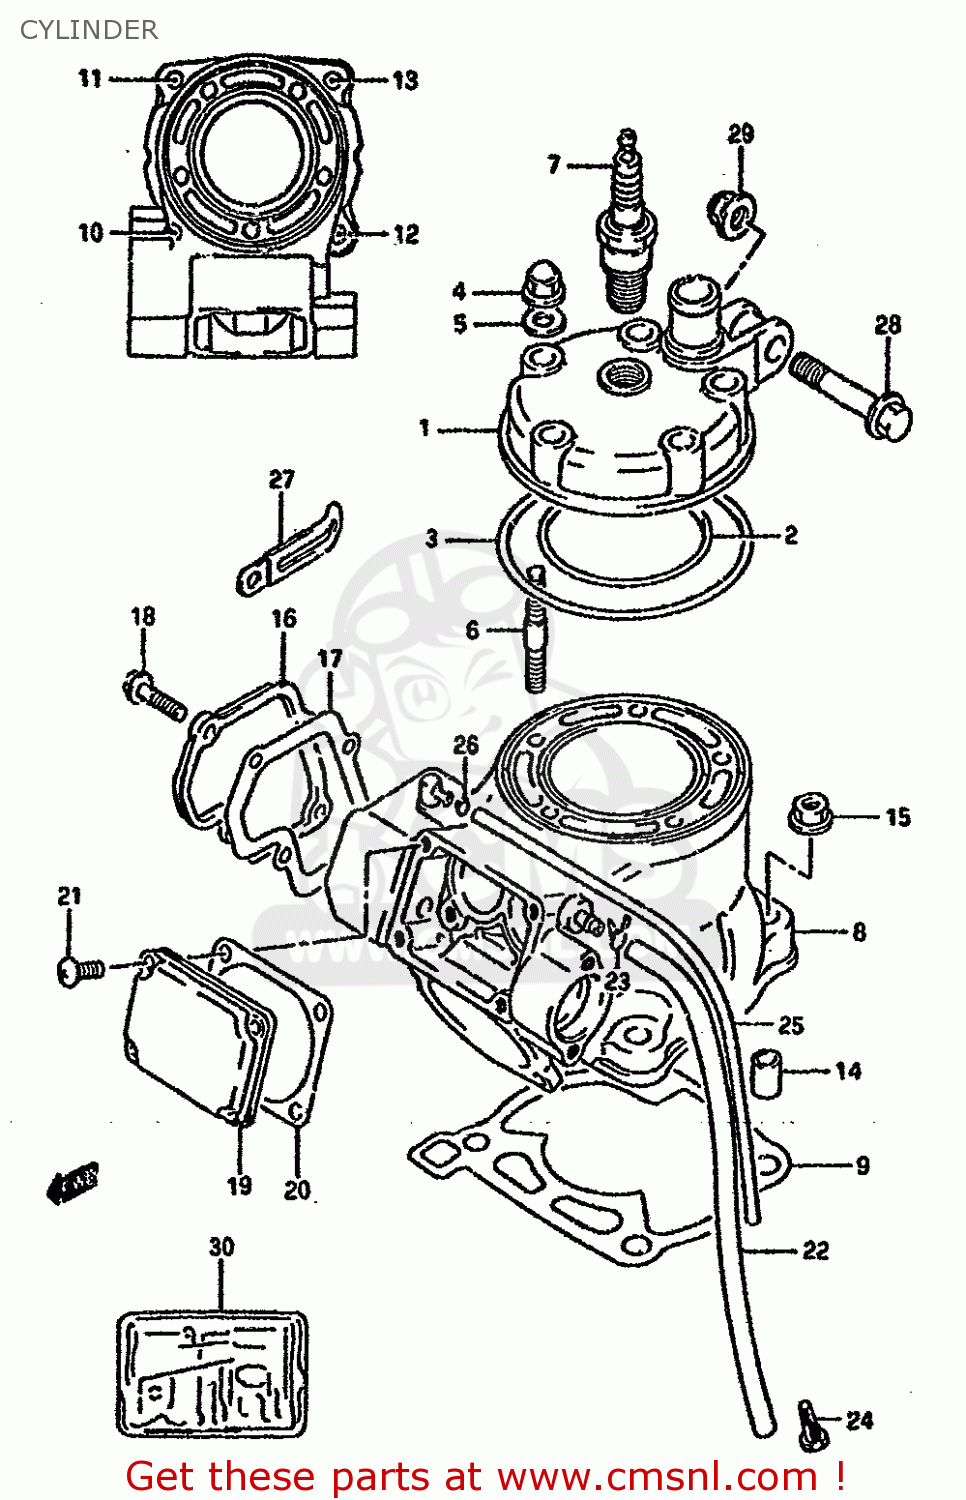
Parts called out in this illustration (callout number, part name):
1	HEAD,CYLINDER
2	O RING,CYLINDER HEAD NO.1
3	O RING,CYLINDER HEAD NO.2
4	NUT
5	GASKET(8.5X17X2.3) (NAS)
6	BOLT,STUD
7	SPARK PLUG BR9EV
8	CYLINDER
9	GASKET,CYLINDER (NAS)
10	STUD 8X25
11	BOLT,STUD
12	STUD BOLT
13	BOLT,STUD
14	PIN(8.4X11X14)
15	NUT
16	COVER,CYLINDER NO.1
17	GASKET,CYLINDER COVER (NAS)
18	BOLT
19	COVER,CYLINDER NO.2
20	GASKET,CYLINDER COVER NO.2 (NAS)
21	BOLT
22	HOSE
23	CLIP
24	FILTER,EXH VALVE BREATHER HOSE
25	HOSE(5X8.2X600)
26	CLIP
27	CLAMP
28	BOLT(8X41)
29	NUT
30	GASKET SET (NAS)
